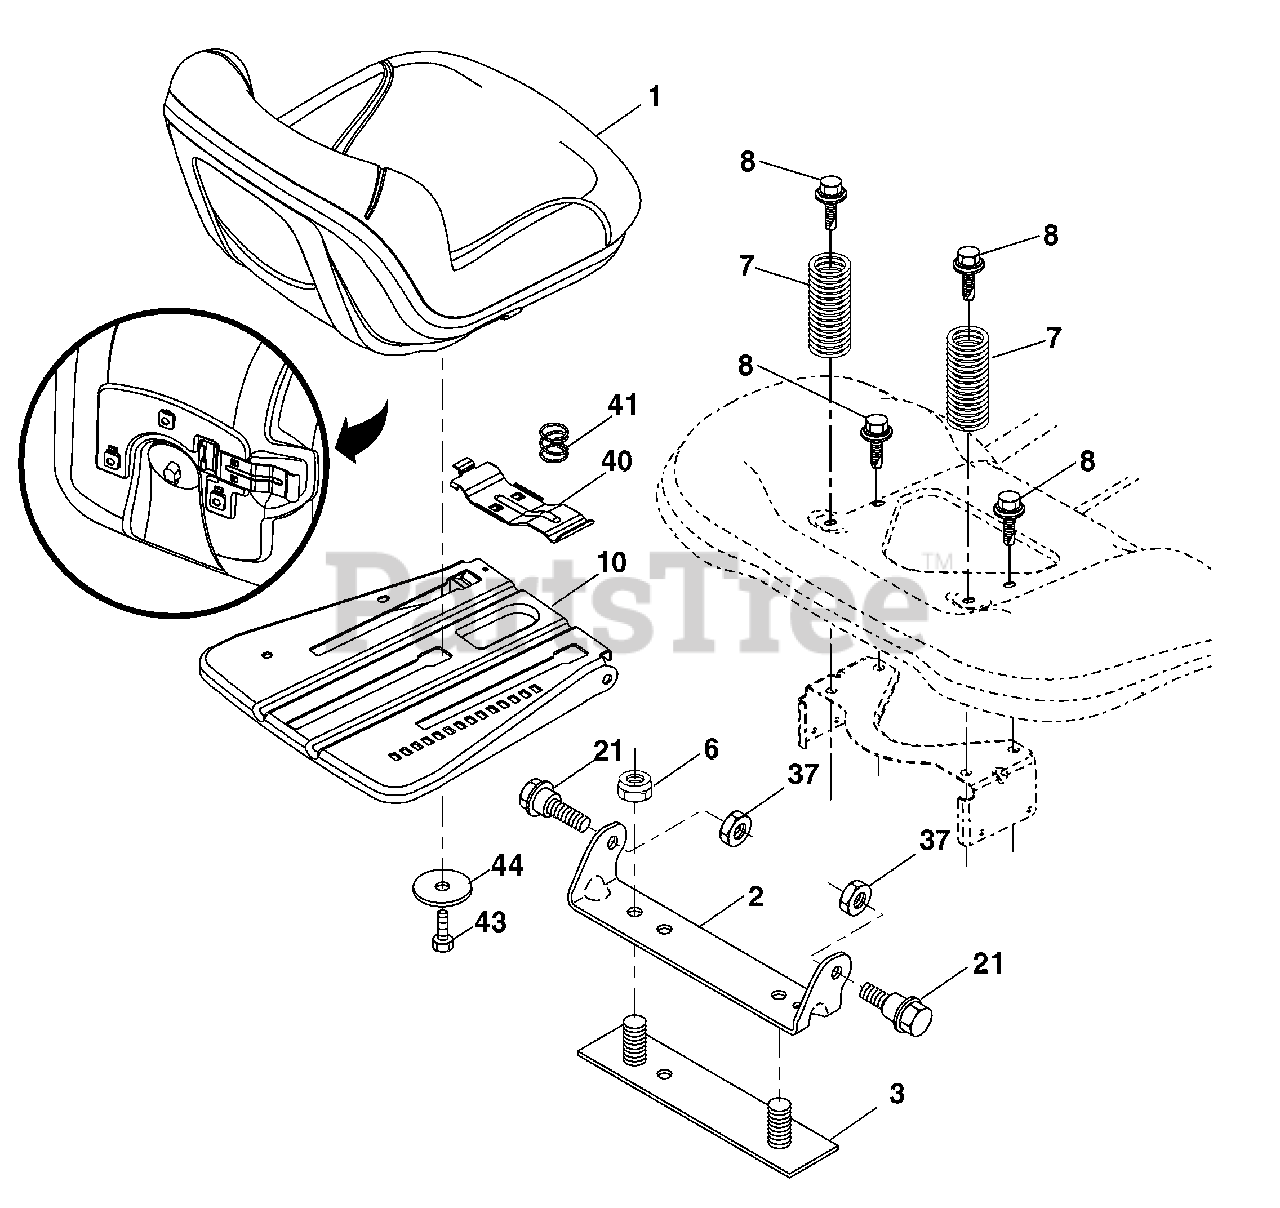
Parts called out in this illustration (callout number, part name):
1	Seat
2	Bracket Pivot Fender
3	Strap, Asm Fender
6	Nut, Lock w/Ins. 3/8-16 unc
7	Spring, Seat Cprsn
8	Bolt 5/16-18 unc x 3/4 w/Sems
10	Pan, Seat
21	Bolt, Shoulder 5/16-18
37	Nut, Lock 5/16-18 unc
40	Handle Slide Seat
41	Spring Latch Seat
43	Bolt 3/8-16 x 3/4
44	Washer 13/32 x 2-3/8 x 12 Ga.
